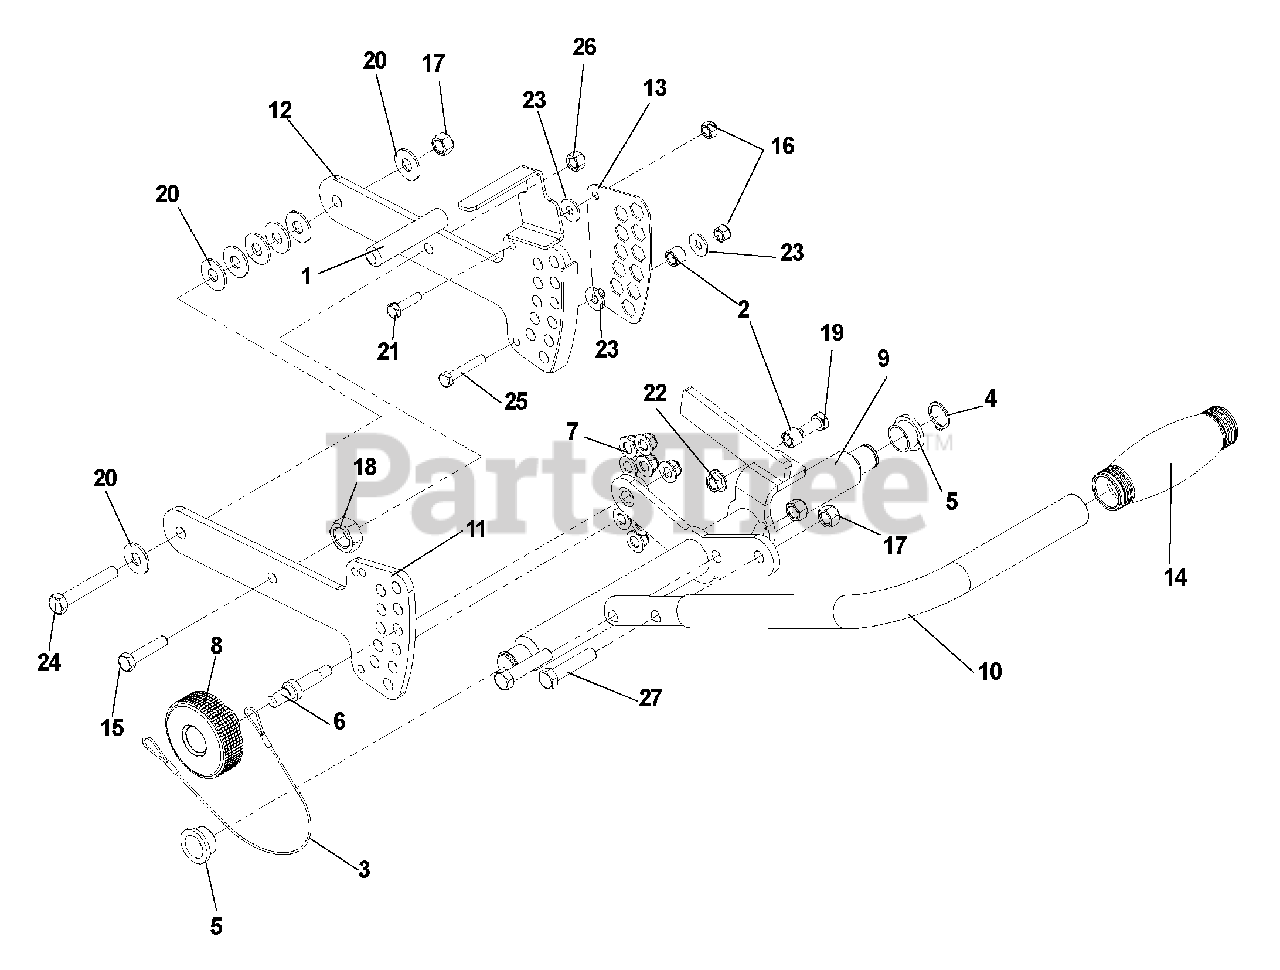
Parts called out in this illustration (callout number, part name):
1	GRIP, VINYL
4	SNAP RING, 3/4
5	BEARING, FLANGE
6	STUD, ADJUSTER
7	NUT, 5/16-18, NYLOC
8	KNOB
9	SHAFT
11	ADJUSTER
12	ADJUSTER, RIGHT
13	PLATE - ADJUSTER NUT
14	GRIP HANDLE
15	HCS, 5/16-18 X 1 1/2, GR5
16	NUT, 1/4-20, NYLOC
17	NUT, 3/8-16, NYLOC
18	NUT, 5/8-18
19	HCS, 5/16-18 X 3/4, GR5
20	WASHER, 3/8
21	HCS, 1/4-20 X 1, GR5
22	NUT, 5/16-18, WHIZLK
23	WASHER, 1/4
24	HCS, 3/8-16 X 2 1/4, GR5
25	HCS, 1/4-20 X 1 1/2, GR5
26	NUT, 5/16-18, NYLOC
27	HCS, 3/8-16 X 1 3/4, GR5
